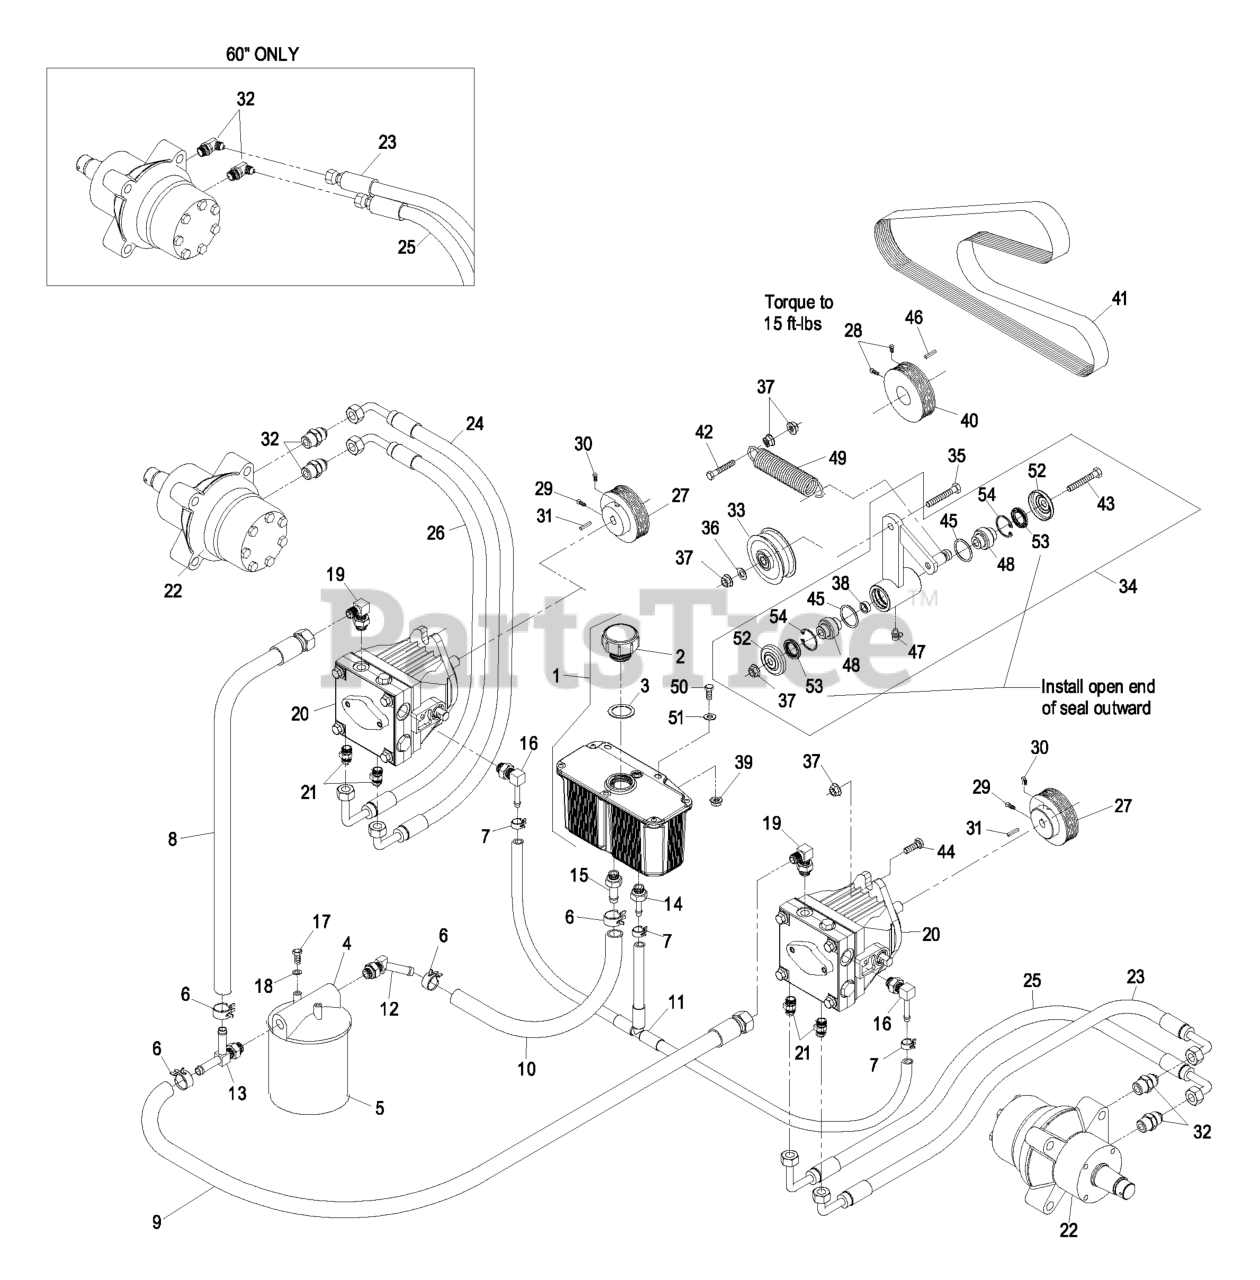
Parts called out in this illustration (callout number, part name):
1	HYD RESERVOIR ASM
2	Cap-Reservoir, HYD
3	GASKET-CAP
4	HEAD-FILTER
6	CLAMP-HOSE
7	CLAMP-HOSE
8	HYD HOSE ASM
9	HYD HOSE ASM
10	HOSE-HYD
11	HYD HOSE ASM
12	FITTING-BARBED, 45 DEG
13	ADAPTER-RUN, TEE
14	ADAPTER-STRAIGHT
15	ADAPTER-STRAIGHT
16	ELBOW-90 DEG
17	SCREW-HH
18	WASHER-LOCK
19	FITTING-ELBOW, 90 DEG
21	FITTING-STRAIGHT
22	MOTOR-WHEEL
23	HYD HOSE ASM
24	HYD HOSE ASM
25	HYD HOSE ASM
26	HYD HOSE ASM
28	SCREW-SET
29	SCREW-SET
30	SCREW-SET
31	KEY-SQUARE
32	FITTING-STRAIGHT
33	SHEAVE-IDLER
34	KIT,PUMP IDLER LZ
35	SCREW-HH
36	WASHER-FLAT
37	NUT-HHF, WHIZ
41	BELT, POLY-V K
42	SCREW-HH
43	SCREW-HH
44	SCREW-HH
46	KEY-SQUARE
47	FITTING-GREASE, 90 DEG
48	BEARING-SPHERICAL
50	SCREW-HH
51	WASHER-FLAT
52	GUARD-TOP
53	SEAL-LIP, SINGLE
54	RING-SNAP
